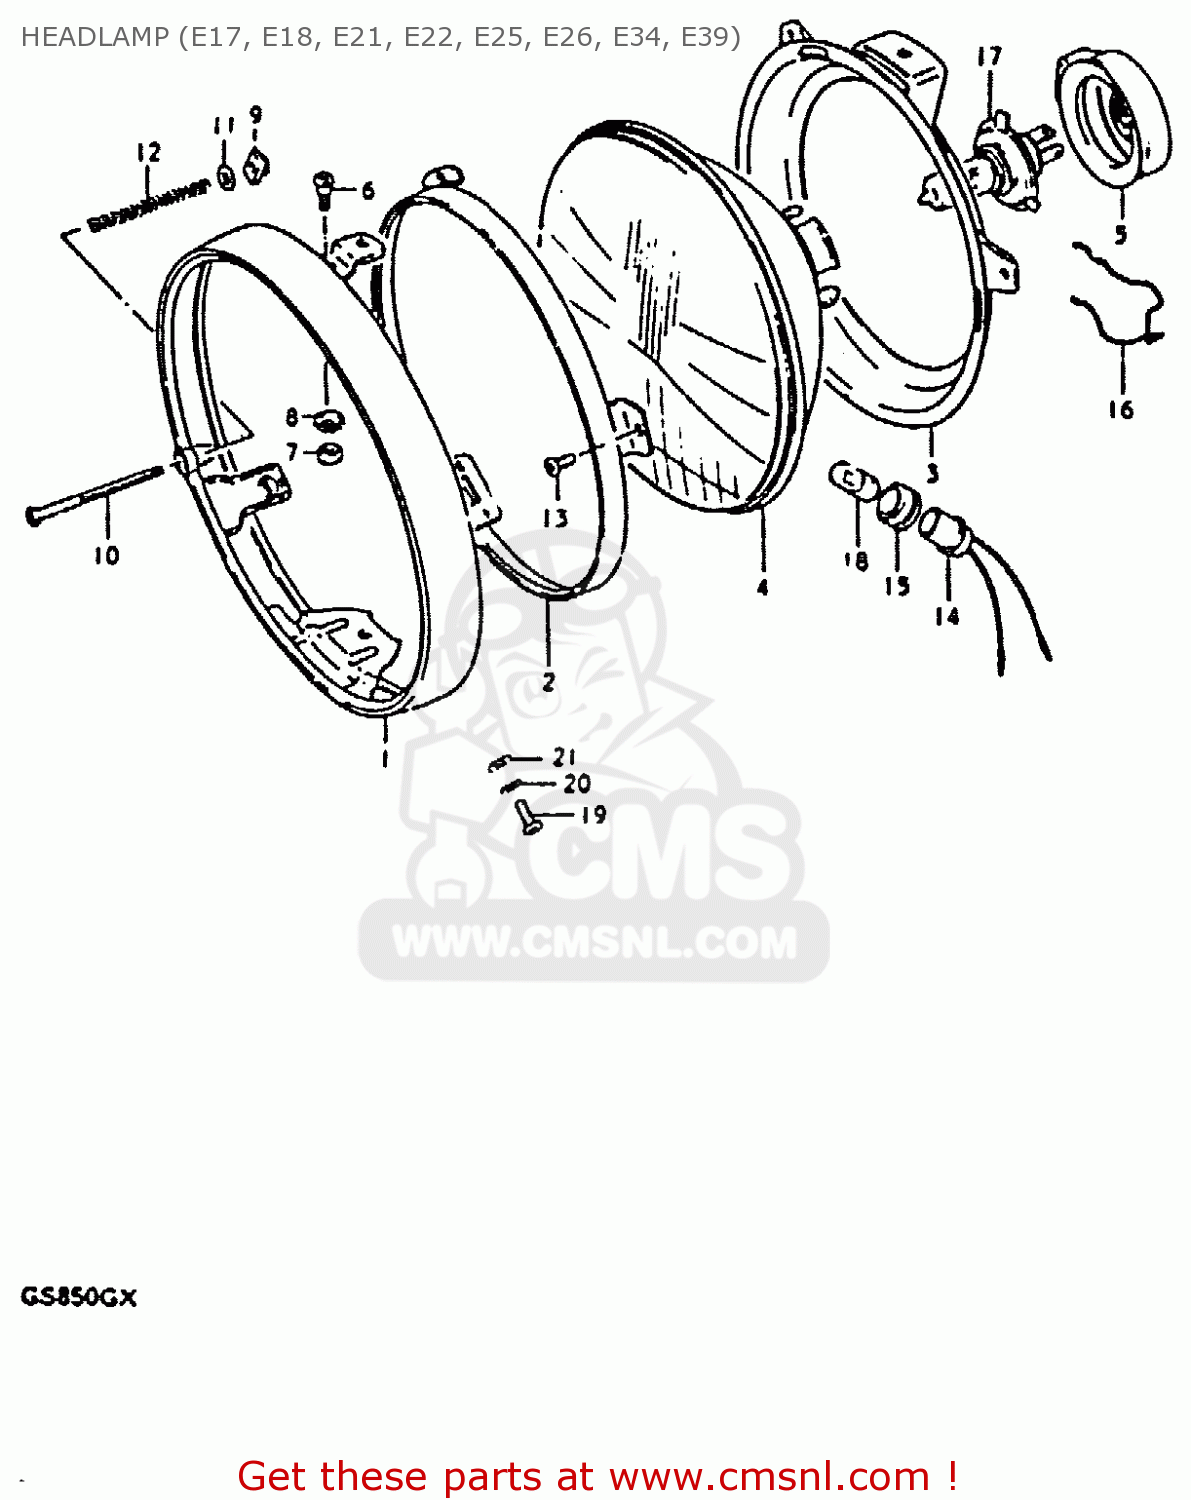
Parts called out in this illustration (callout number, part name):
1	RIM
2	RETAINER
3	RING,HEADLAMP UNIT
4	UNIT,HEAD LAMP
5	COVER,HEADLAMP SOCKET
6	SCREW
7	NUT,ADJUSTING
8	SPACER
9	NUT
10	SCREW,HEADLAMP ADJUST
11	WASHER
12	SPRING,HEADLAMP ADJUST
13	SCREW
14	SOCKET
15	JOINT,RUBBER
16	CLAMP,HEADLAMP SOCKET
17	BULB(12V60/55W,H4)
18	BULB(12V4W)
19	SCREW
20	WASHER,LOCK
21	WASHER
